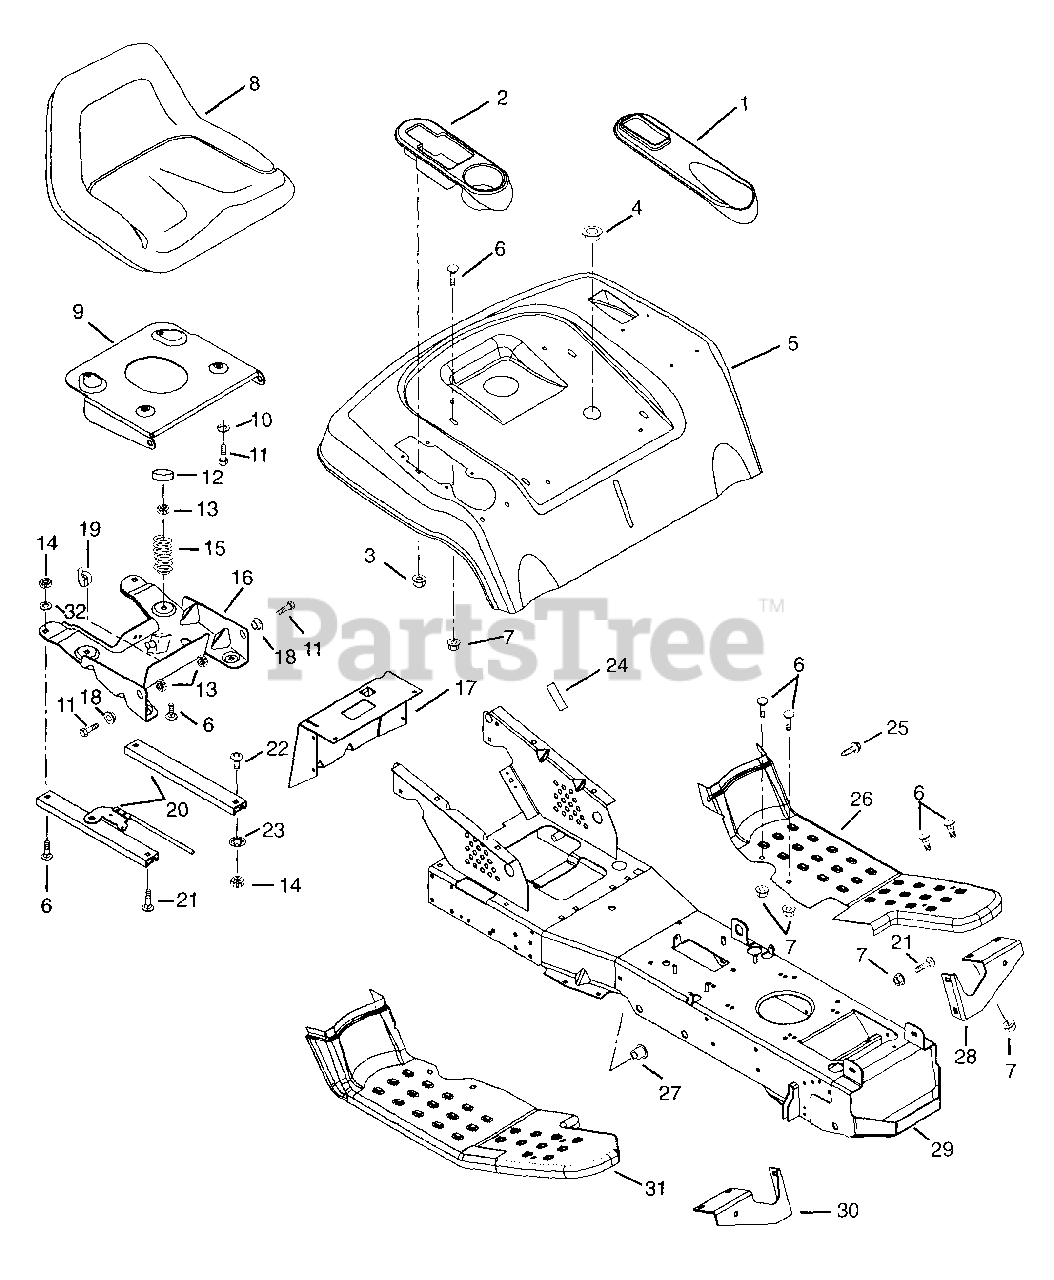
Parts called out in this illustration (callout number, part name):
1	INSERT- LIFT
2	INSERT - BEVERAGE
3	NUT-SELF-THRDNG FITS.25 STUDPL
4	SNAP BUSHING
5	REAR DECK
6	@BLT-RHDSSQNK .31-18X.62 G5YZ
7	@NUT-SPNLK-FLG .312-18 YWZC
8	SEAT V-1500 HI WELTLESS
9	SEAT PIVOT PLATE
10	WSHR-LK .312X.097 HVY YWZC
11	@BLT-HEX .31-18X.75 GR5 YWZC
12	TUBE CAP
13	@NUT-LK-CTR .31-18 YWZC
14	@NUT-HEX .31-18 YWZC
15	SG-COMP .148X1.23X2.41 WLD87
16	BOX, SEAT
17	DRAWBAR
18	BSHG-FLG .325X.465X.333X.685
19	CLIP-HARNESS TINNERMAN
20	SEAT SLIDES -(RAME TAK-3010-4)
21	BLT-RDHDSQSHK.31-18X.75 GR2 YW
22	SCR-CAP BTHD.31-18X.50 GR5 YZ
23	WSHR-LK-INT .313X.030 PL
24	PAD, FOAM
25	@SCR-TAP .31-18X.50 HWH TR YWZ
26	FOOTREST- LH
27	BSHG-FLG .515X.750X.745X1.00NY
28	BRACE - FOOT REST L.H.
29	FRAME, MAIN
30	BRACE - FOOT REST R.H.
31	FOOTREST- RH HYDRO
32	@WSHR-LK .31X.078 REG YWZC
